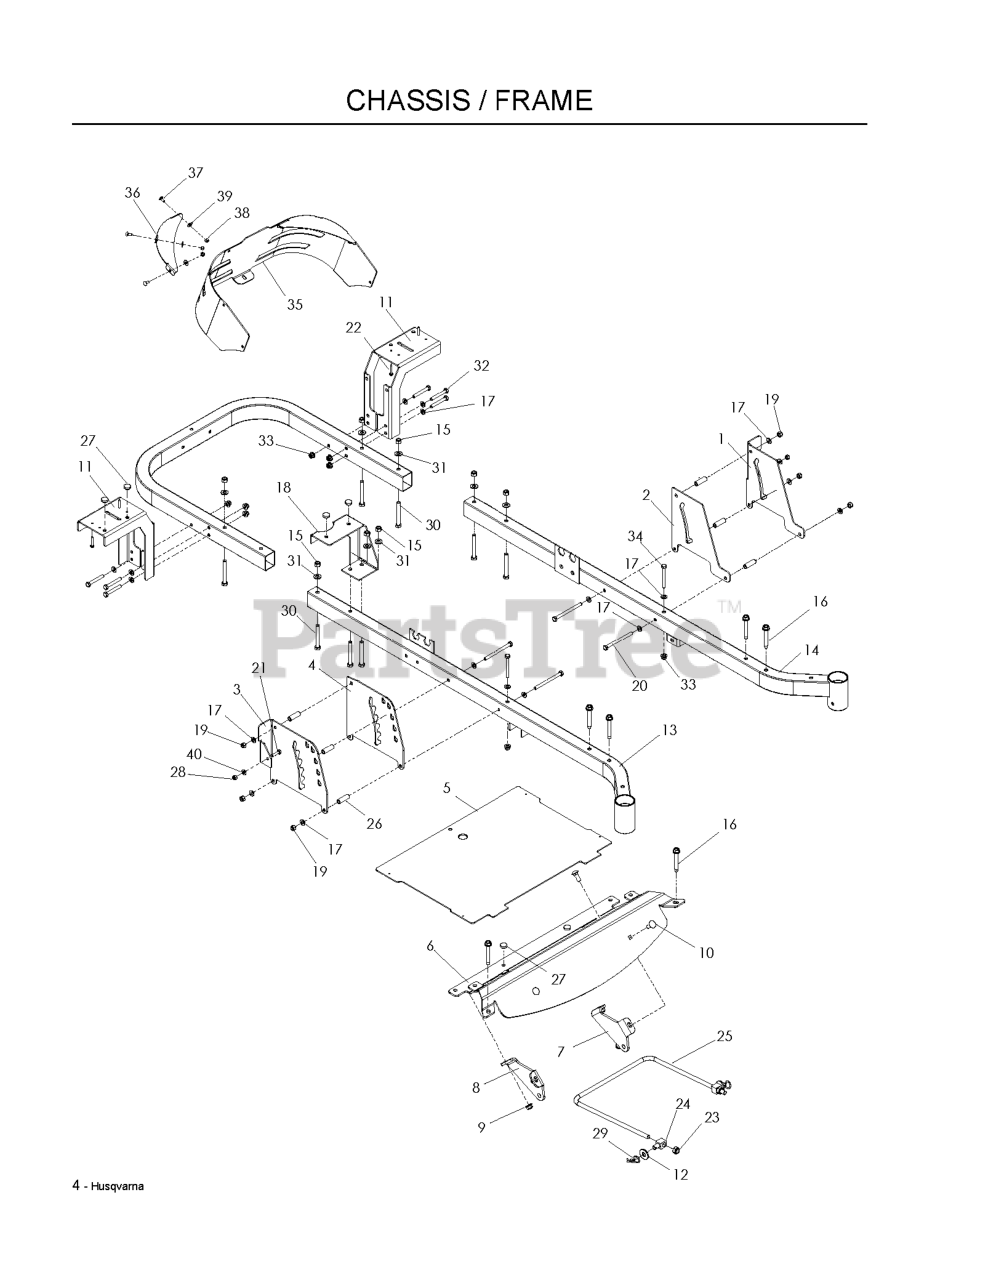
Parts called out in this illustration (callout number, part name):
1	PLATE, OUTER BRAKE, BLACK
2	PLATE, BRAKE LATCH, BLACK
3	PLATE, HEIGHT ADJ, BLACK
4	PLATE, DECK HEIGHT, BLACK
5	PLATE, FOOT W/DECALS EZ
6	FOOT REST WIDE ORG
7	MOUNT, STRUT, RT, BLK
8	MOUNT, STRUT, LT, BLK
9	NUT 3/8-16 HEX FLG NYLOC ZD
10	RHSNB 3/8C X 1
11	SUPPORT, FENDER, BLACK
12	WASH USS FLAT 1/2
13	FRAME, RT, ORANGE
14	FRAME, LT, ORANGE
15	NUT 3/8-16 NYLOC
16	ENGINE BOLT, SPECIAL
17	FLAT WASHER 5/16 SAE
18	SUPPORT, TANK, BLACK
19	NUT 5/16 NYLOC
20	HCS 5/16C X 4
21	HCS 1/4C X 1
22	SCR #10-12X1-1/2HEX WASH HD ZD
23	7/16-14 HEX NUT W/NYL RING ZD
25	LINK, FRONT SUSP.
26	SPACER, .334 ID X .5 OD X 1.5
27	GROMMET, BUMPER
28	NUT.1/4-20.HEX.NYLOC.ZD
29	HAIRPIN #4
30	HCS 3/8C X 3
31	WASHER 3/8 SAE FLAT
33	5/16-18 NYLOC FLANGE NUT
34	HCS 5/16C X 2-3/4
35	GUARD, REAR, ORANGE
36	SUPPORT, CORNER, ORANGE
37	RHSSNB, 1/4-20X5/8
38	NUT.1/4-20.HEX.NYLOC.ZD
39	WASHER 1/4 FLAT
40	WASHER 1/4 SAE
